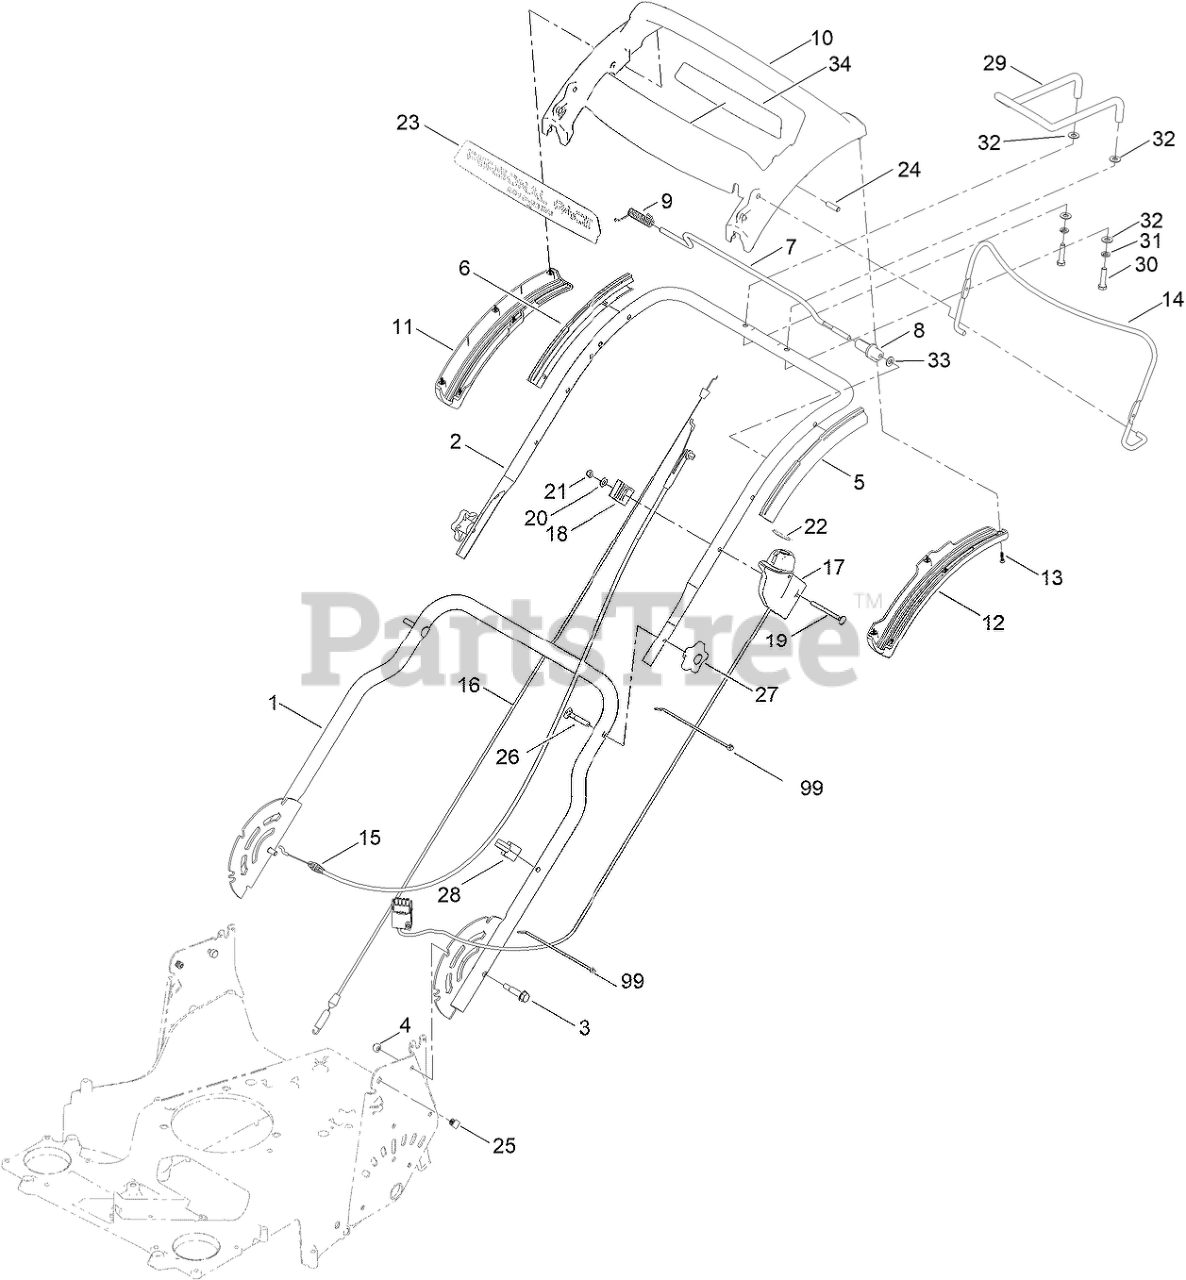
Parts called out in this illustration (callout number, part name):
1	HANDLE-LOWER, ASM
2	HANDLE-UPPER
3	BOLT-SHOULDER, HHF
4	NUT-HEX
5	GUIDE-CURVED, LH (RWD)
6	GUIDE-CURVED, RH (RWD)
7	ROD-CONTROL, TRACTION
8	LEVER-TRACTION, RWD
9	SPRING-TORSION
10	HANDLE-PERSONAL PACE, CURVED
11	BOTTOM-HANDLE, RH
12	BOTTOM-HANDLE, LH
13	SCREW-PPH
14	BAIL-BRAKE
15	CABLE-BRAKE, PP BS
16	CABLE-TRACTION
17	STARTER SWITCH ASM
18	CLAMP-CABLE
19	SCREW-HANDLE
20	WASHER-FLAT
21	NUT-HEX
22	DECAL-CONTROLS
23	DECAL-HANDLE, PP
24	PIN-HANDLE, PP
25	PLUG-SQUARE
26	SCREW-HANDLE
27	KNOB-HANDLE
28	GUIDE-CABLE
29	HANDLE-ASSIST, STEEL
30	SCREW-HH
31	WASHER-LOCK
32	WASHER
33	WASHER-PLAIN
34	DECAL-CONTROLS (60V, START)
99	TIE-CABLE
